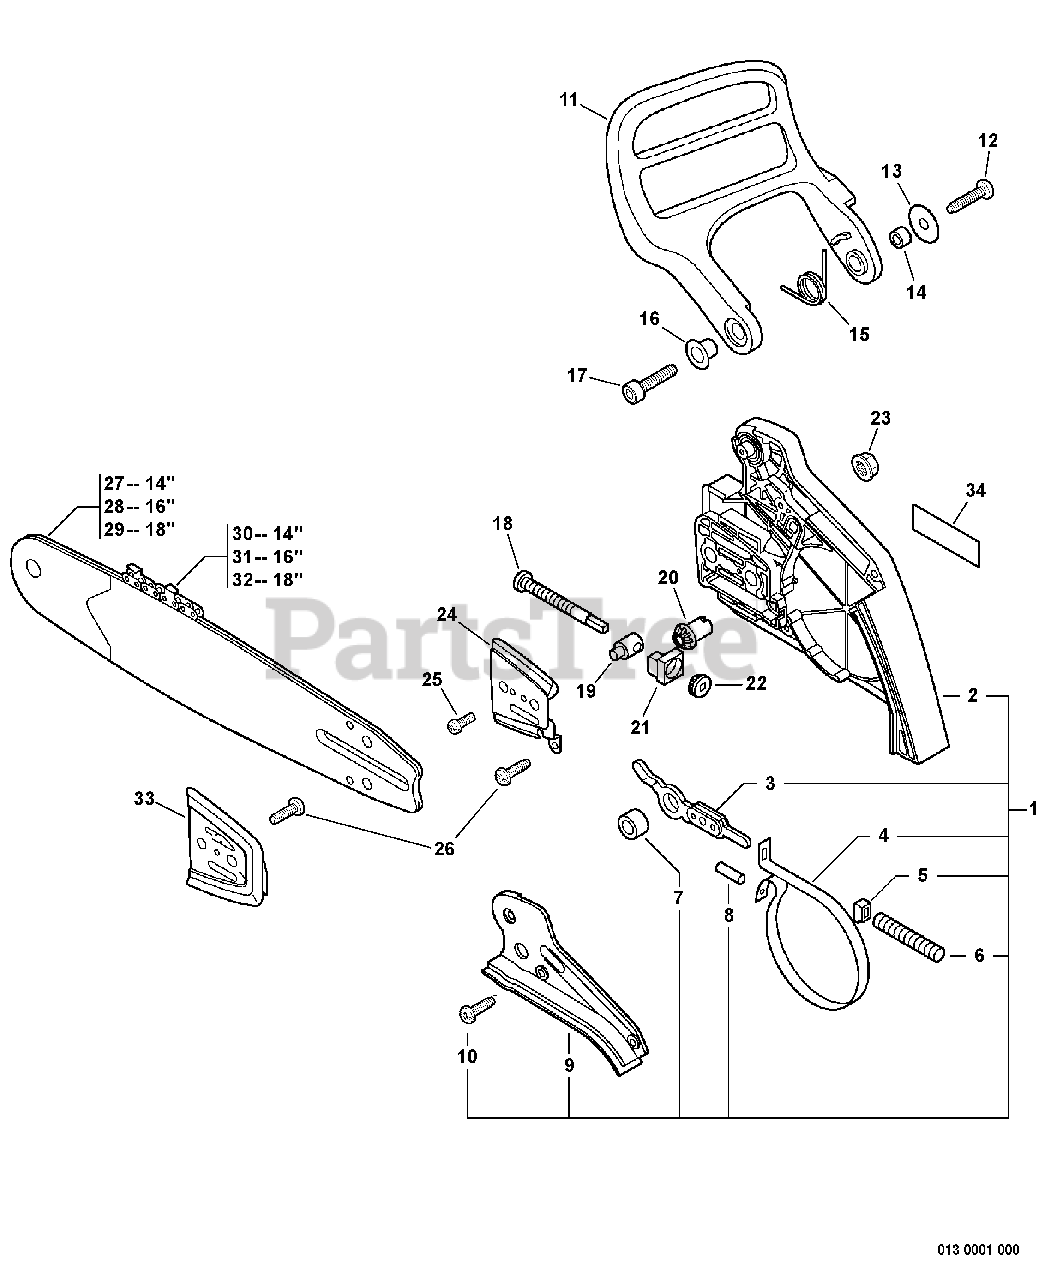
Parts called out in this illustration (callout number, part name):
1	CHAIN BRAKE ASSY
2	GUARD, SPROCKET
3	CONNECTOR, BRAKE
4	BAND, BRAKE
6	SPRING, COMPRESSION
7	SPACER 8×12×9
8	PIN, SPRING 3x-9.8
9	COVER, BRAKE
10	SCREW 4×12
11	LEVER, BRAKE
12	SCREW 4×16
13	WASHER 4.2×16.5×1
14	SPACER 8×12×9
15	SPRING, TORSION
16	COLLAR 10
17	SCREW TAPPING 5×16
18	SCREW, CHAIN TENSION
19	TENSIONER, CHAIN
20	GEAR, BEVEL
21	COLLAR 8
22	GEAR, BEVEL
23	NUT, FLANGE M8×1.25
24	PLATE, GUIDE - OUTER
25	SCREW 3×6
26	SCREW 4×8
27	GUIDE BAR, 14" DOUBLE-GUARD
28	GUIDE BAR, 16" DOUBLE-GUARD
29	GUIDE BAR, 18" DOUBLE-GUARD
30	SAW CHAIN 14" XTRAGUARD
31	SAW CHAIN 16"
32	SAW CHAIN 18"
33	PLATE, GUIDE - INNER
34	LABEL - ECHO
